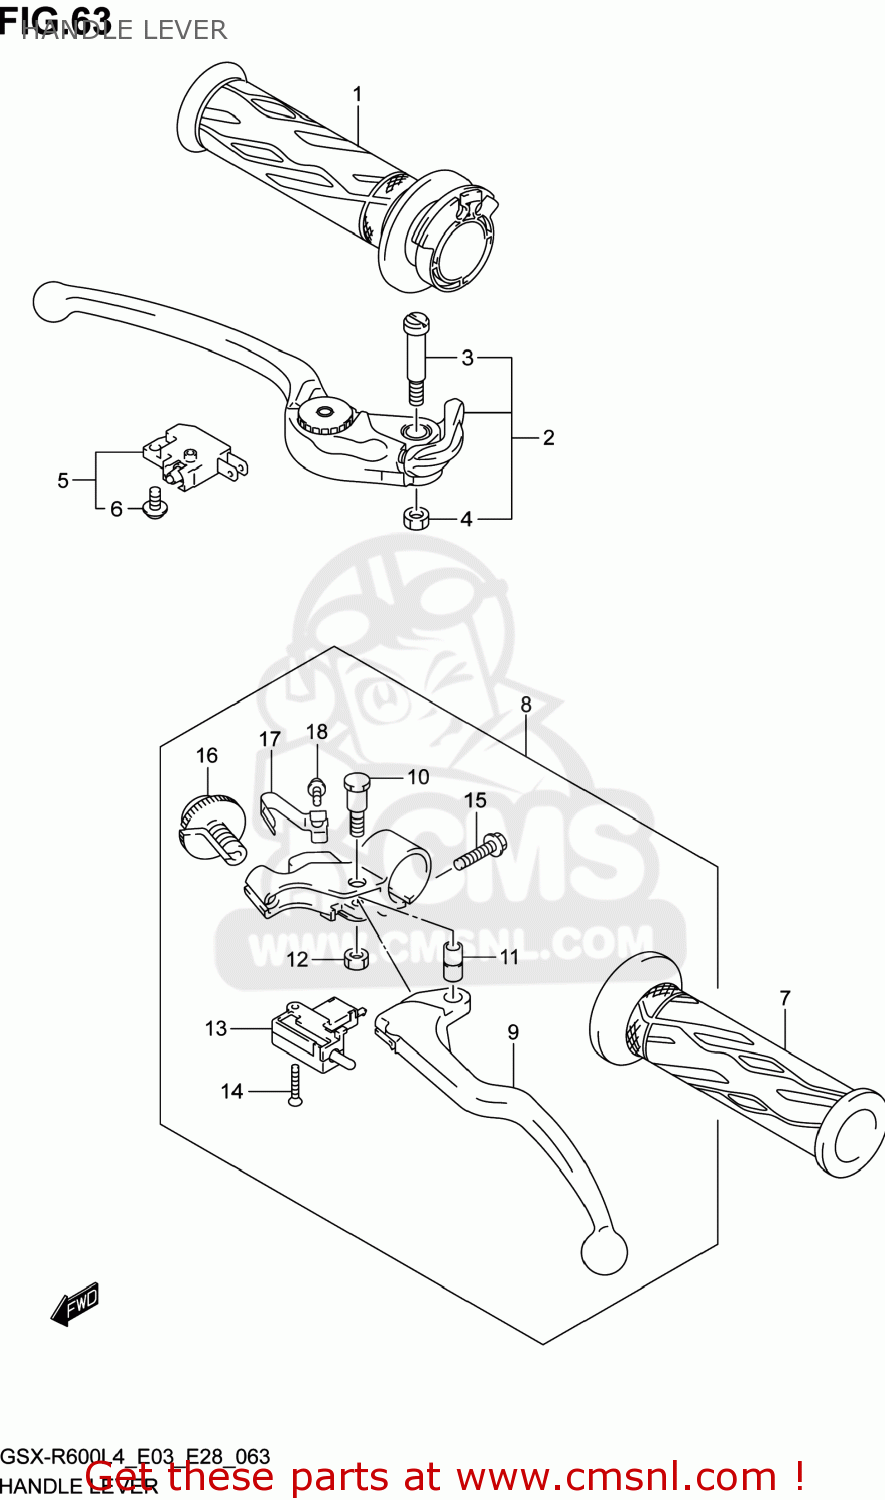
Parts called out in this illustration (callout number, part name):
1	GRIP,THROTTLE
2	LEVER ASSY,BRAKE
3	BOLT,LEVER PIVOT
4	NUT
5	SWITCH ASSY,FR BRAKE
6	SCREW
7	GRIP,L
8	LEVER ASSY,CLUTCH
9	LEVER,CLUTCH
10	BOLT,CLUTCH LEVER PIVOT
11	COLLAR
12	NUT
13	SWITCH,CLUTCH
14	SCREW
15	BOLT
16	NUT,ADJUSTER
17	SPRING,ADJUST
18	SCREW,SPRING
